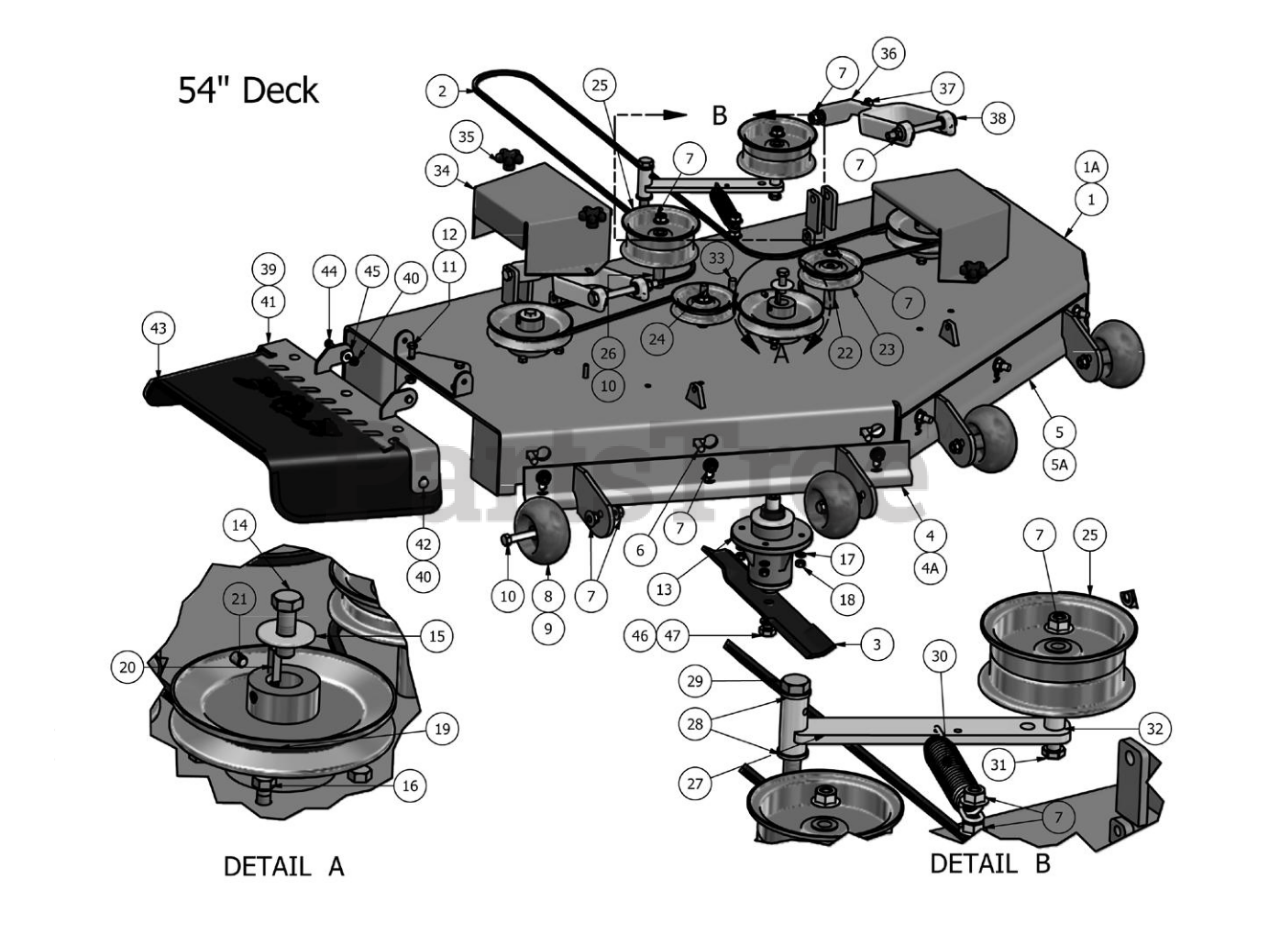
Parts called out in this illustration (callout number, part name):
1	54 Outlaw Deck (component)
1A	54 Outlaw Deck
2	B165 Belt- 60 Pup/Lightning/ZT/54 Outlaw
3	18 3/4" Blade
4	54 Outlaw Adjustable Deck Front (Right Component)
4A	54 Outlaw Adjustable Deck Front (Right)
5	54 Outlaw Adjustable Deck Front (Left Component)
5A	54 Outlaw Adjustable Deck Front (Left)
6	1/2 x 1-1/4 Carriage Bolt
7	1/2-13 Nylon Insert Flange Nut Zinc Orange
8	Anti-Scalp Rollers
9	Deck Wheel Assembly
10	1/2" x 4" Bolt (Grade 8)
11	3/8" x 3/4" Hex Bolt
12	3/8" Flange Nut
13	Double Bearing Spindle
14	1/2" x 1 1/2" Hex Bolt
15	Spring Blade Cupped Washer
16	3/8-16 x 1-1/4 GR 5 Hex Bolt Zinc
17	3/8" Lock Washer
18	3/8" Hex Nut
19	6 1/4" Drive Pulley
20	1/4" x 1" Key
21	3/8" Set Screw
22	Pup Pulley Spacer
23	4 3/4" Idler Pulley
24	1/2 x 3-1/2 Flange Bolt - Grade 8
25	5 3/4" Deck Idler Pulley
26	1 3/4" Pulley Spacer
27	Deck Idler 2009
28	.635 ID Plastic Washer
29	5/8" x 4" Hex Bolt
30	Deck Idler Spring 2009
31	1/2" x 3" Hex Bolt
32	3/4 OD × 1/2 ID x 3\4 Length
33	1/2 x 2" Carriage Bolt
34	Plastic Pulley Cover
35	5/16" Knob
36	Deck Arm Assembly
37	1/2 x 2-1/2 Hex Bolt
38	1/2" x 5 1/2" Bolt
39	60" Lower Hanger
40	5/16-18 Nylon Insert Flange Nut Zinc Orange
41	60" Discharge Chute Upper Hanger Plate
42	5/16" x 1 1/4" Carriage Bolt
43	Rubber Discharge Chute
44	5/16-18 x 1 Grade 5 Hex bolt Zinc
45	.360ID Plastic Washer
46	5/8" Lock Washer
47	5/8" x 1 1/2" Grade 8 Bolt
